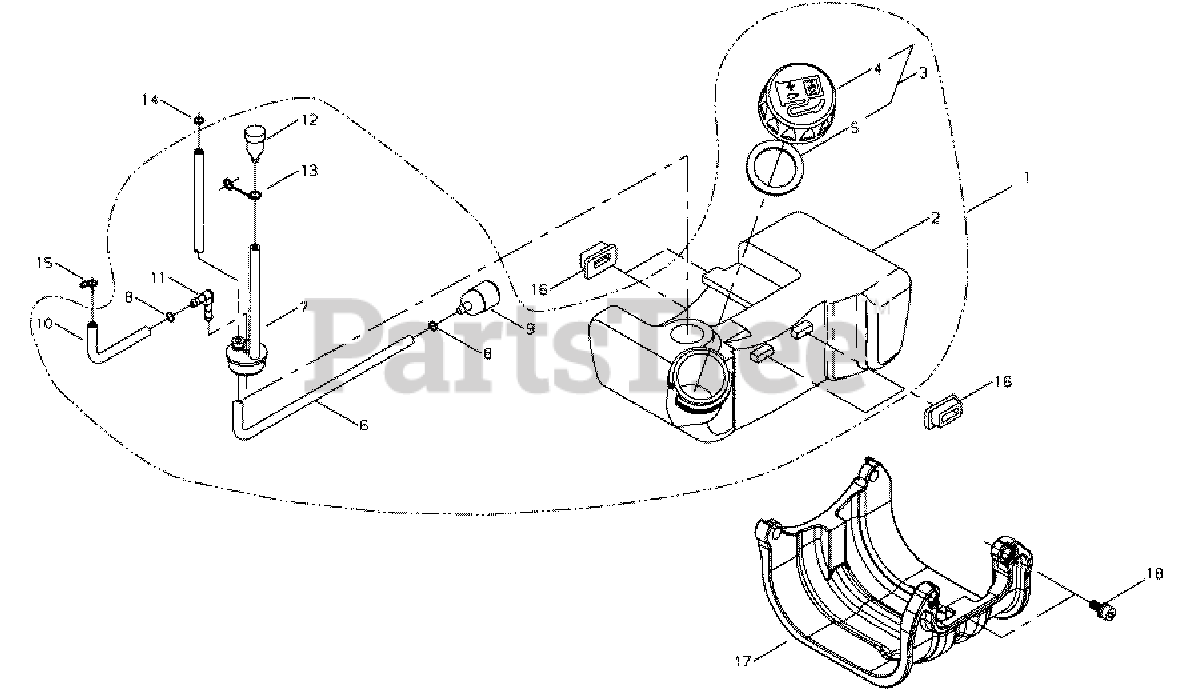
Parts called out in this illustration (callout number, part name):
1	FUEL TANK ASSY
2	TANK, FUEL
3	CAP ASSY
4	CAP, FUEL
5	GASKET, CAP
6	PIPE - FUEL
7	VENT PIPE ASSY
8	RING, RETAINING - 6
9	FILTER, FUEL
10	PIPE - RETURN
11	CONNECTOR, PIPE
12	VENT, FUEL TANK
13	HOLDER, VENT
14	RING, RETAINING - 6
15	CLIP - SPRING
16	CUSHION, TANK
17	GUARD, FUEL TANK
18	SCREW - 5X18
